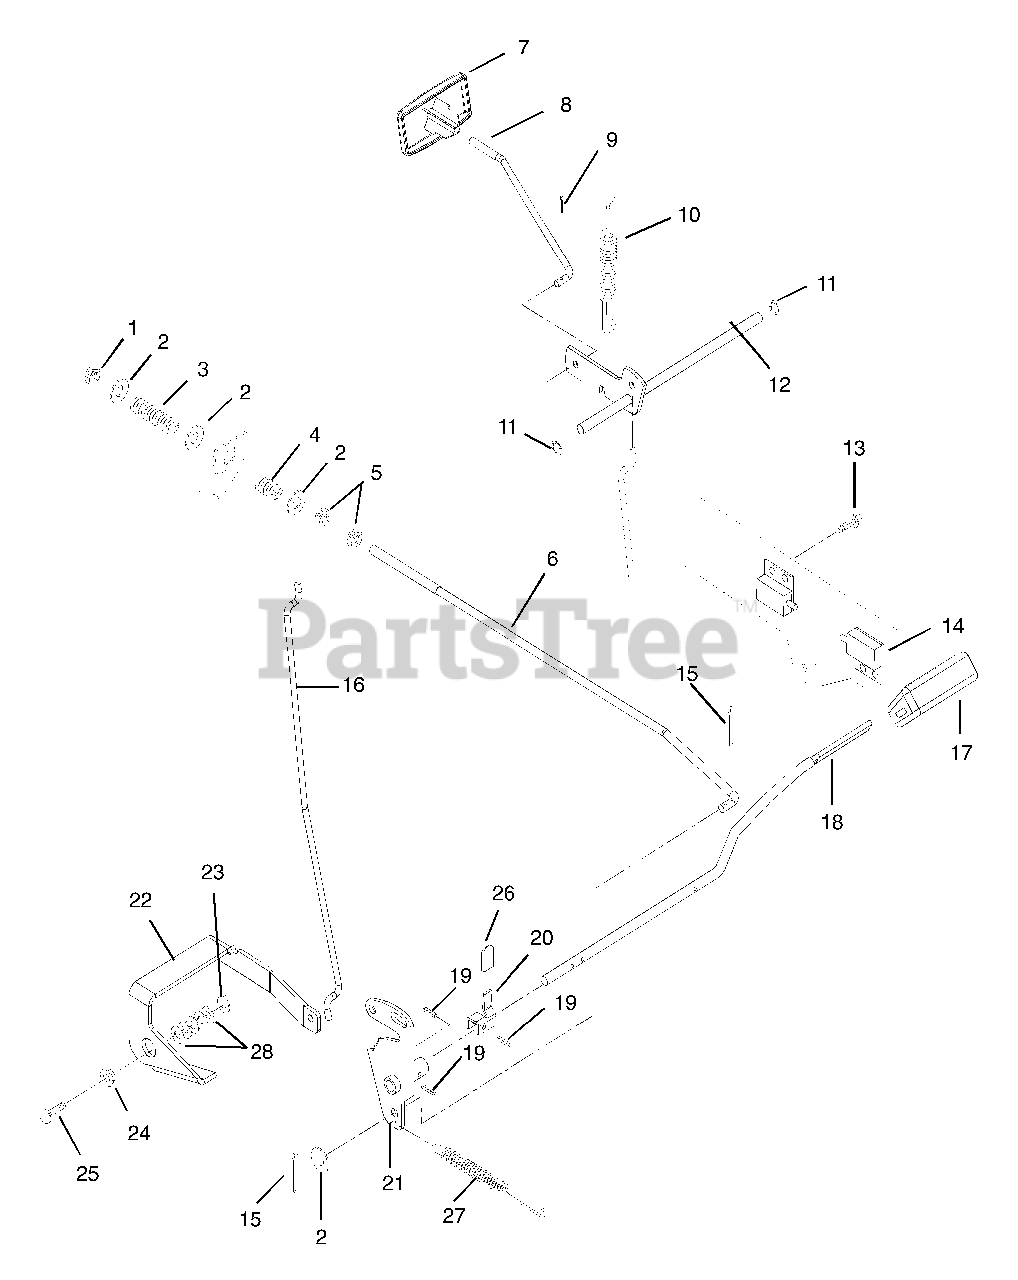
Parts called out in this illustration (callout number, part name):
1	@NUT-LK-CTR-JAM .375-16 YWZC
2	@WSHR-FL-STL.406X.812X.065 YWZ
3	SG-COMP .048X.59X2.06 WLD9
4	SG-COMP .125X.78X1.00 YWZ
5	NUT-HEX-JAM .375-16 YWZC
6	ROD - BRAKE
7	KNOB, PARK BRAKE
8	ROD, PARKING BRAKE
9	PIN-COTR .06X.50
10	SG-TENS .051X.60X2.25 WLD 7.0
11	RG-RTNG-EXT .250X.010
12	BELLCRANK-PARKING BRAKE
13	@SCR-TAP 12-24X.50 HWH TR YWZC
14	SWITCH- SINGLE POLE N.O.
15	@PIN-CTR .09X.75 EXTPRSQCT YWZ
16	ROD, PARKING BRAKE
17	COVER - PEDAL - BRAKE
18	PEDAL - BRAKE
19	PIN-GRV .188X1.25 TP A
20	LEVER - BRAKE SWITCH
21	ARM + HUB - BRAKE
22	LEVER, PARKING BRAKE
23	@NUT-LK-CTR .31-18 YWZC
24	BSHG, FLG .325X.499X.26X.88
25	BLT-RDHDSQSHK.31-18X.75 GR2 YW
26	GRIP .062 X .375 X 1.000 RE
27	SG-TENS .105X.85X5.00 WLD 40
28	WSHR-PLASTIC .390X.875X.062
